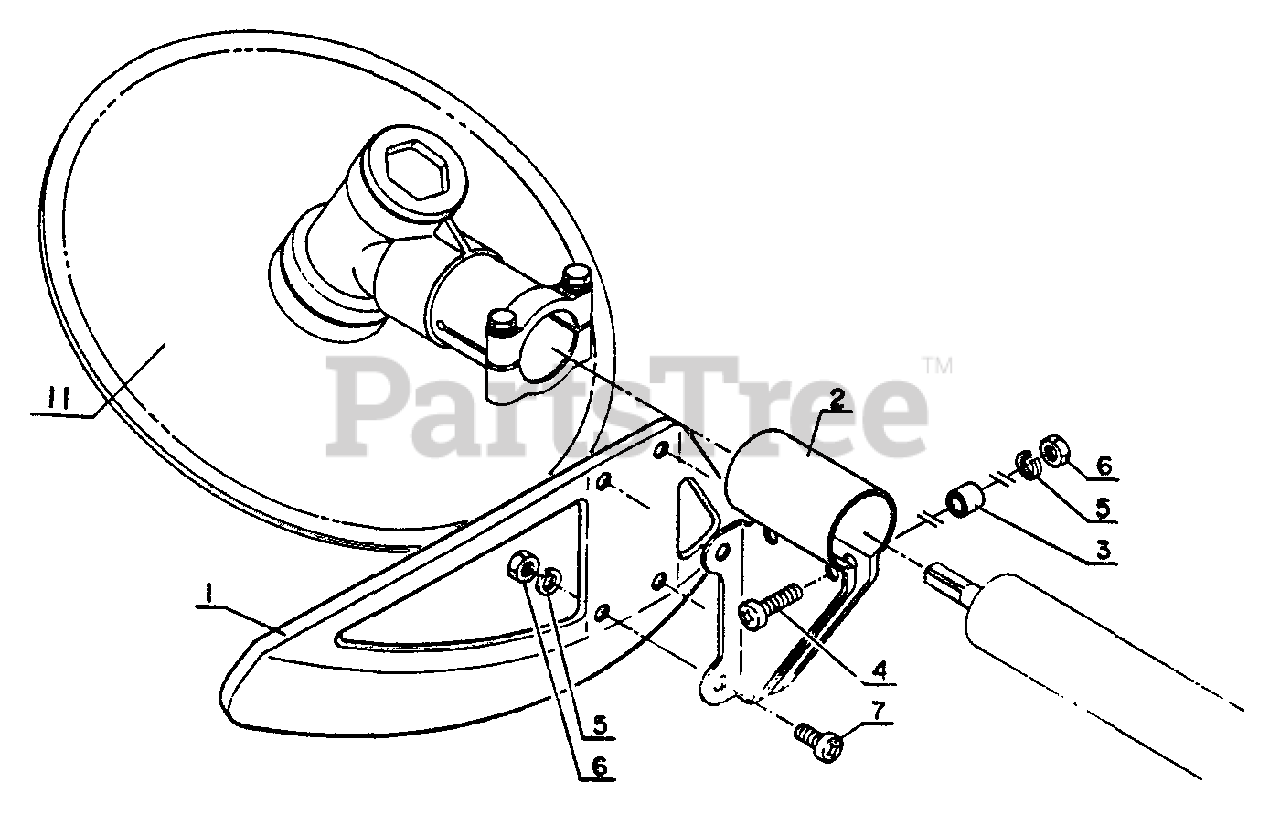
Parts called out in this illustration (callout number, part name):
1	SAFETY GUARD
2	SAFETY GUARD SET PLATE
3	SPACER, GUARD
4	SCREW - 5×18
5	WASHER, SPRING 5
6	NUT M5
7	SCREW - 5×8
11	SAW, CIRCULAR
